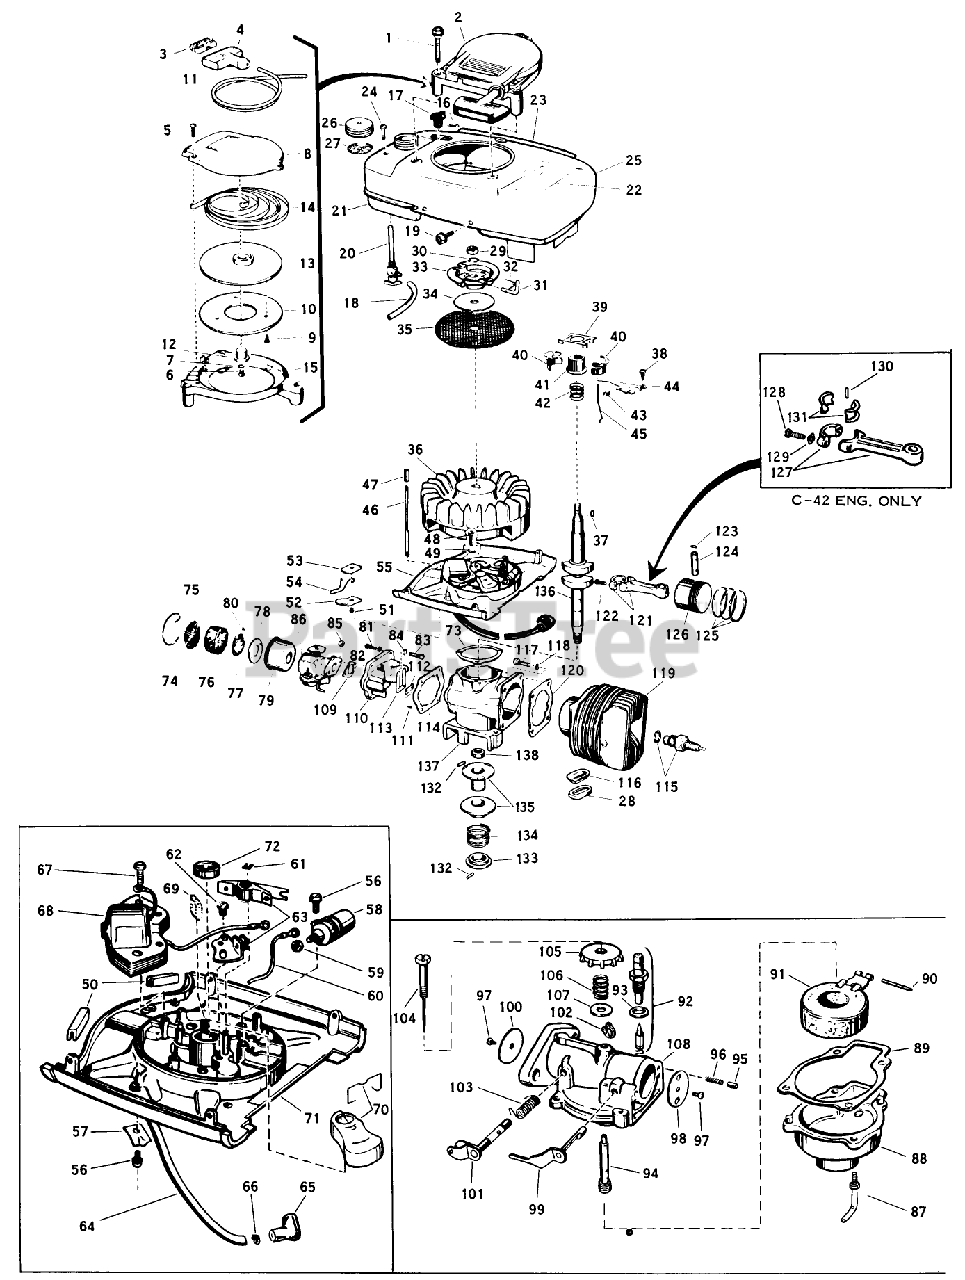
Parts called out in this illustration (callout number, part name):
10	Plate-Pulley
14	RECOIL SPRING
16	Cotter Pin-Choke Knob
17	KNOB, CHOKE BAR
19	SCREW S
20	VALVE&SCREEN SM
22	Decal-Instruction
23	Decal-"Lawn-Boy"
26	Gas Cap
31	PIN - STARTER
41	COLLAR S
43	WEAR BLOCK S
44	GOVERNER LEVER AY
45	GOVERNOR ROD S
51	Screw Shut-off Switch
61	Spring Clip-Breaker Post
63	BREAKER AY. S
65	Cover-Rubber
73	GASKET S
76	ELEMENT
78	BACK-UP PLATE
81	SCREW S
85	STOP NUT
97	Screw-Choke Disc
99	CHOKE SHAFT&LVR AY
103	SPRING
104	NEEDLE AY. S
106	Spring-Ndl. Adj.
109	GASKET S
112	PLATE-BACKUP, REED
114	GASKET
115	Spark Plug
122	Screw-Connecting Rod
128	SCREW
131	LINER ASM
132	Pin-Pulley Drive
133	Retainer-Spring (Drive Pulley)
134	Spring-Comp. (Drive Pulley)
136	Crankshaft
136	Crankshaft-C-42 Engine
